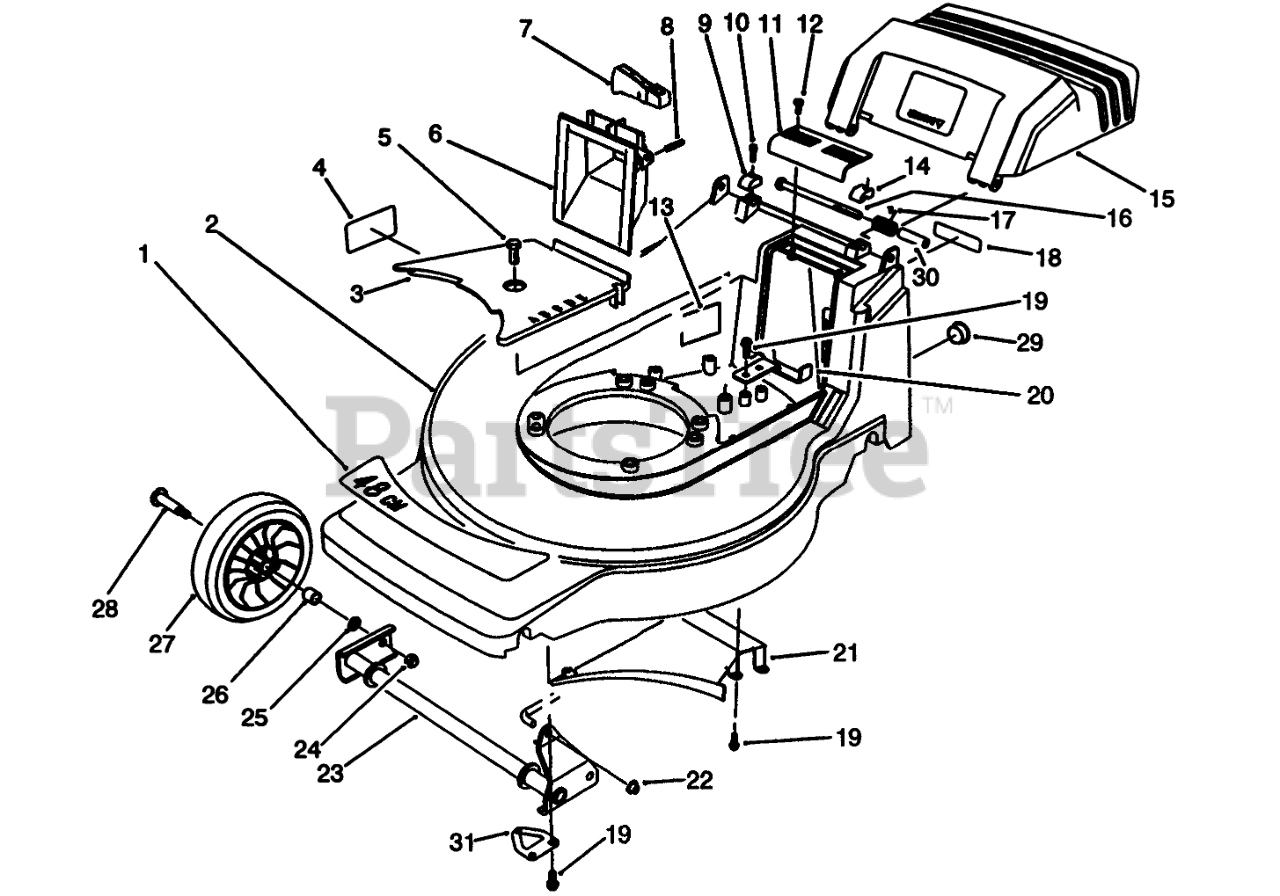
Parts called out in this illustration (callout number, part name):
1	DECAL - DECK
2	Housing-48cm (Incl. Ref. #1, 4, & 13)
3	BELT COVER
4	Decal Danger
5	SCREW-HWHTF
6	GRIP - LOWER
7	TRIGGER - HOC
8	PIN-SPIRAL
9	CAP-HINGE BOLT, RH
10	SCREW-HSH
11	GRIP-UPPER
12	SCREW-PPH, PLASTITE
13	Decal-Noise
14	CAP-HINGE BOLT, LH
15	Door-Discharge
16	SCREW-HH
17	DOOR SPRING
18	DECAL FRENCH REGUL.
19	SCREW-HWH
20	REAR BELT GUIDE
21	Ramp-Discharge
22	NUT-PUSH
23	FRONT PIVOT WA
24	NUT-HEX
25	WASHER
26	BUSHING
27	Wheel & Tire Assembly (Incl. Ref. #26)
28	BOLT-WHEEL
29	DOME PLUG (DP-1000)
30	SPACER-DOOR
31	LH AXLE RETAINER
